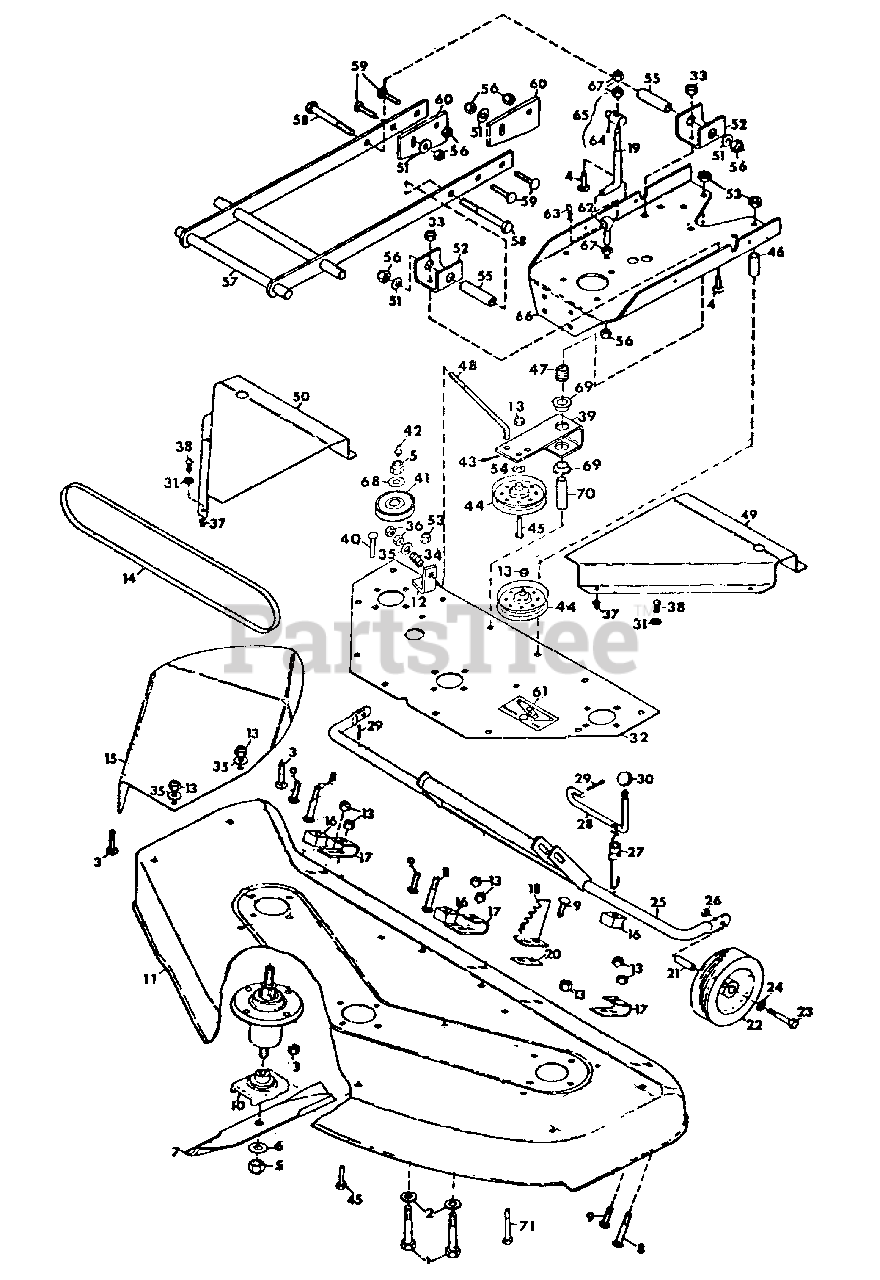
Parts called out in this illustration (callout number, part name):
1	BOLT, HEX 1/2-13X3.75
2	WASHER, FLAT .531X1.062X.095
3	BOLT, 3/8-16X.75 RD. HD. SQ. NK.
4	BOLT, HEX 5/16-18X.875
5	NUT, LOCK 5/8-11
6	WASHER, FLAT .656X1.312X.095
7	BLADE
8	BOLT, 3/8-16X2 RD. HD. SQ. NK.
9	BOLT, 3/8-16X1 RD. HD. SQ. NK.
10	CRADLE, BLADE
11	WELDMENT, 40 IN. DECK
12	SUPPORT, SPRING
13	NUT, LOCK 3/8-16
14	BELT, 40" MOWER
15	SHIELD, SAFETY EXTENSION
16	STOP, NYLON
17	BRACKET, AXLE SUPPORT
18	BRACKET, HEIGHT ADJUST
19	ROD, LIFT
20	SHIM, MOWER HT. ADJ. BKT.
21	BUSHING, .750X.375X1.785
22	WHEEL, GAUGE
23	BOLT, HEX 3/8-16X2.5
24	WASHER, FLAT .438X1.375X.083
25	AXLE, PIVOT WELDMENT
26	NUT, JAM 3/8-16
27	SPRING, 40 & 50 INCH MOWER
28	LEVER, HEIGHT ADJUST.
29	PIN, COTTER 1/8X1.25
30	KNOB, ADJ. CONTROL
31	WASHER, FLAT .281X.625X.065
32	PLATE, SUPPORT
33	NUT, LOCK 5/16-18
34	SPRING, COMP. 1X.78X.338 LB/IN
35	WASHER, FLAT .406X.812X.065
36	NUT, HEX 3/8-24
37	GROMMET, PLASTIC
38	SCREW, MACH. 1/4-20X.62 RD. HD.
39	ARM, IDLER PIVOT
40	BOLT, 3/8-16X1.25 RD. HD. SQ. NK.
41	SHEAVE, SPINDLE
42	FITTING, LUBE 1/8
43	PIN, COTTER 3/32X1.00
44	SHEAVE, IDLER
45	BOLT, HEX 3/8-16X2.00
46	SAPCER, .510X.840X2.43
47	SPRING, COMP.
48	ROD, IDLER
49	COVER, PULLEY L.H. 40
50	COVER, PULLEY R.H. 40
51	WASHER, FLAT .531X1.250X.100
52	SUPPORT, MOWER PIVOT
53	NUT, LOCK 1/2-13
54	SPACER, IDLER .406X.750X.188
55	BUSHING, MOWER PIVOT .510X.750
56	NUT, LOCK 1/2-13
57	WELDMENT, PIVOT ARM
58	BOLT, HEX 1/2-13X3.00
59	BOLT, 1/2-13X1.25 RD. HD. SQ. NK.
60	PLATE, ADJUSTMENT
61	DECAL, BELT INSTALLATION
62	BOLT, EYE
63	COTTER, HAIR PIN
64	PIN, GROOVE .125X.625
65	ASSEMBLY, MOWER LIFT
66	SUPPORT, GEAR HOUSING
67	NUT, JAM 1/2-13
68	WASHER, FLAT .687X1.312X.134
69	BUSHING, NYLON .760X1.00X.600
70	SPACER
71	BOLT, HEX 1/2-13X1.50
